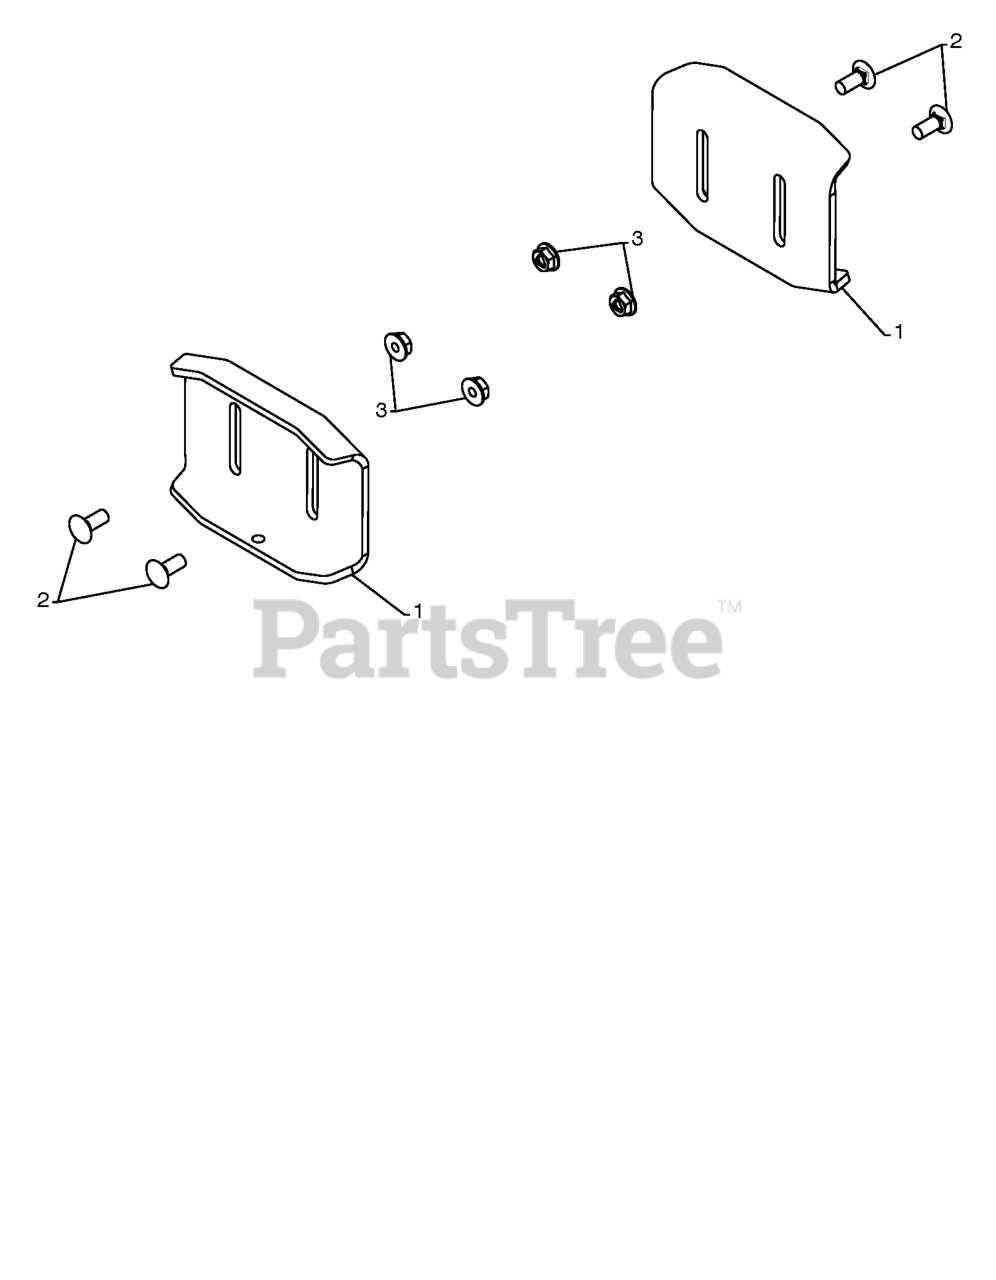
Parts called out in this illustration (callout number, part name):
1	SKID PLATE
2	BOLT
3	NUT.LOCK.5/16-18
